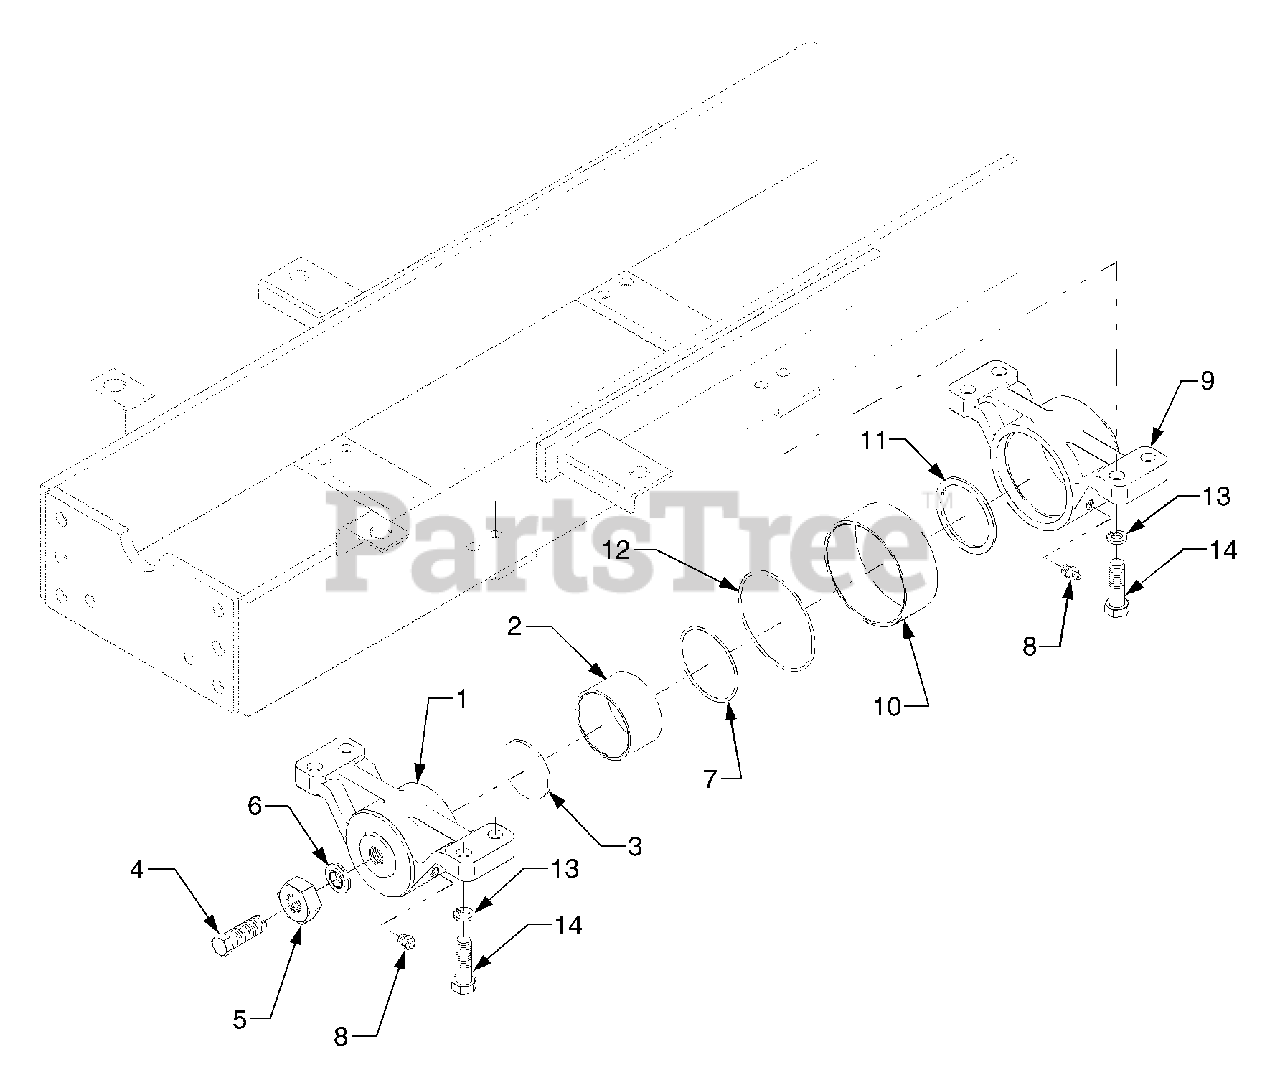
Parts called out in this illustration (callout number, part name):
1	Bracket, Front
8	Nipple, Grease
9	Bracket, Rear
11	Collar, Thrust
14	Washer, Spring
